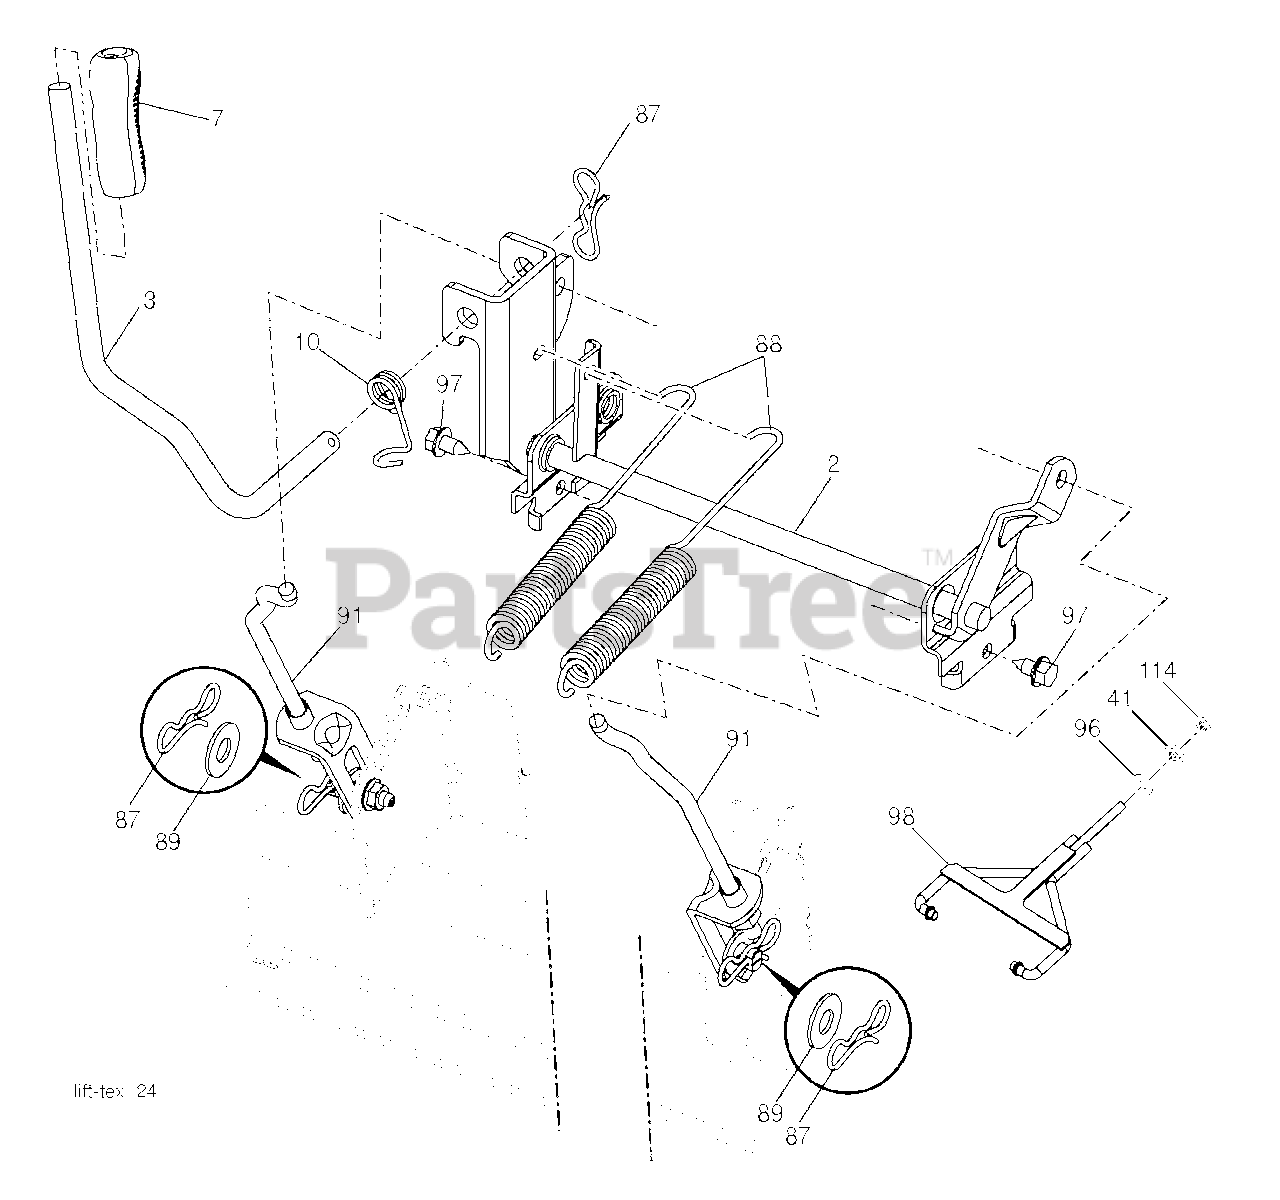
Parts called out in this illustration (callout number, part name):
2	SHAFT.ASM.CROSS.LIFT
3	LEVER.LIFT.HANDLE.GT
7	GRIP.HANDLE.LIFT.PVC.BLACK
10	SPRING.TORSION.LIFT.HANDLE
41	NUT, LIFT LINK 7/16-20
87	PIN.COTTER.7/16.BOW TI.
88	SPRING.LIFT.ASSIST.GT2
89	WASHER.CLEAR.ZINC
91	LINK.ASM.LIFT.54"TG
96	BUSHING SPHERICAL SUSP. FRONT
97	SCREW, 3/8-16X3/4
98	SUSPENSION WLDT FRONT DECK
114	NUT **
